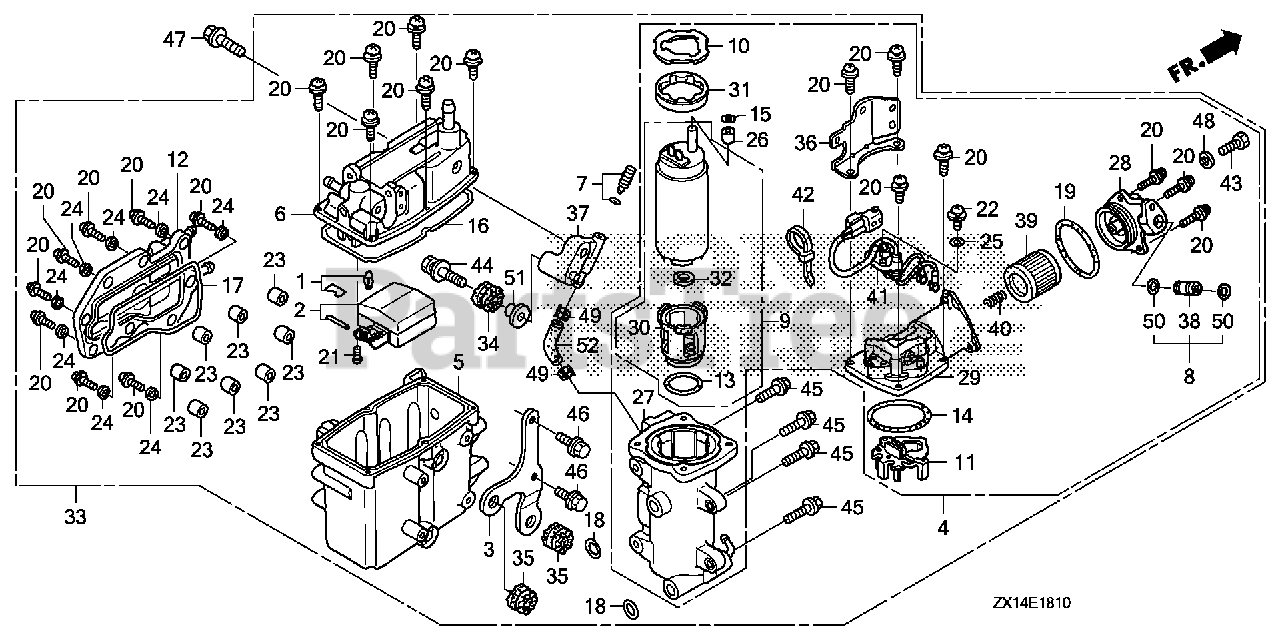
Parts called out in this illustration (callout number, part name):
1	VALVE SET, FLOAT
3	STAY A, PLATE
4	PUMP UNIT, FUEL (MSDS)
5	BODY, CHAMBER
7	SCREW SET, DRAIN (CARBURETOR NO.)
9	PUMP UNIT, FUEL (B) (MSDS)
12	COVER, WATER JACKET
15	O-RING
15	O-RING (7.3X2.2) (NOK)
20	SCREW-WASHER
21	SCREW, PAN
22	SCREW, WASHER
23	COLLAR, SET
24	WASHER, PLAIN
25	WASHER, PLAIN
27	CASE, PUMP
28	COVER B, PUMP
29	COVER, PUMP (A)
33	SEPARATOR ASSY., VAPOR
34	GROMMET, VAPOR SEPARATOR
35	GROMMET, VAPOR SEPARATOR
36	STAY, PLATE
37	STAY, VAPOR SEPARATOR
38	JOINT, FUEL PIPE
39	SCREEN, FUEL STRAINER
40	SPRING, SET
43	BOLT, SEALING (6MM)
44	BOLT-WASHER (8X35)
45	BOLT, FLANGE (6X25)
46	BOLT, FLANGE (6X16)
47	BOLT, FLANGE (8X30)
48	WASHER, SEALING (6MM)
49	CLAMP, TUBE (8.0)
50	O-RING (7.8X1.9) (ARAI)
51	COLLAR (8.5X14.5)
52	TUBE F, FUEL
